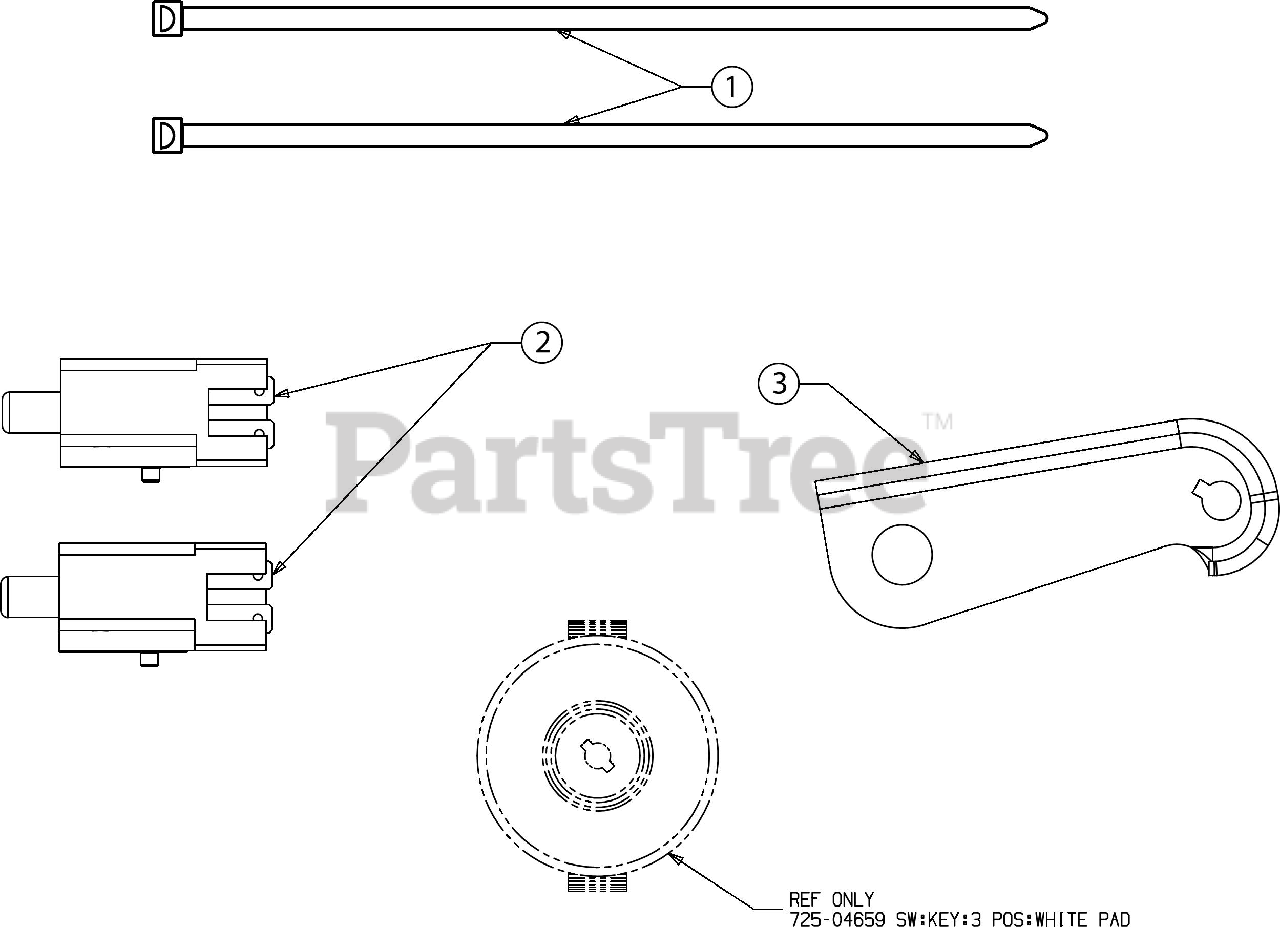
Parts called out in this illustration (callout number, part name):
1	CABLE TIE 7",2"
2	INTERLOCK SWITCH (NO/NC)
3	HARNESS
4	LATCH SPEED BRACKET
